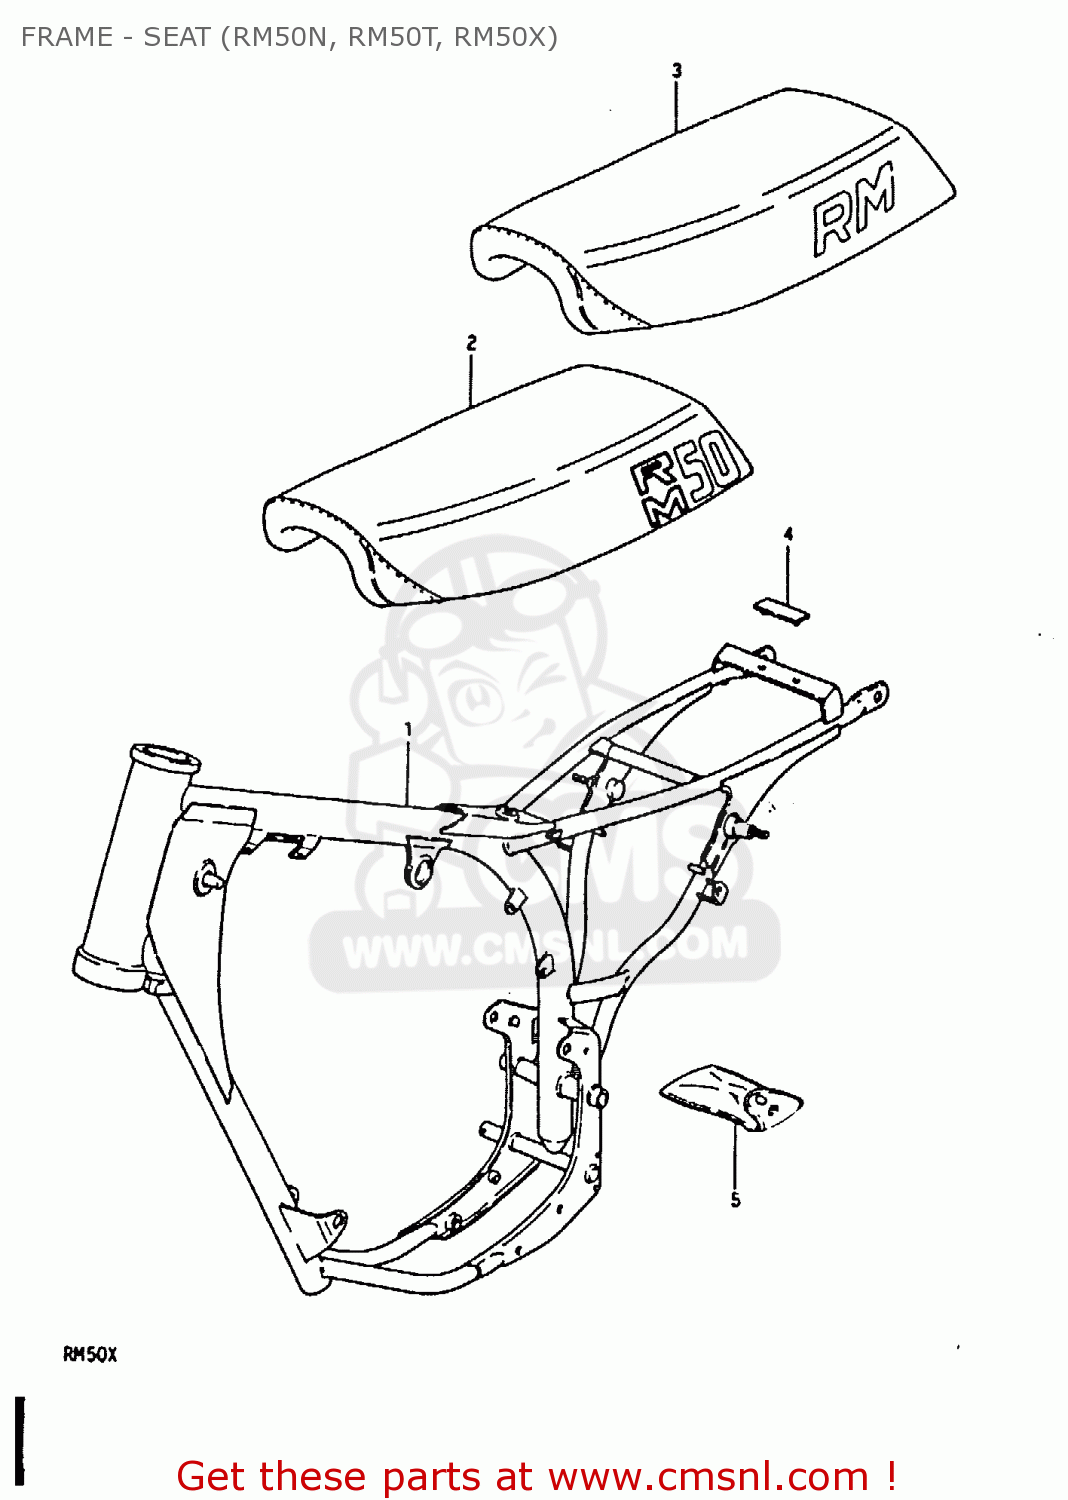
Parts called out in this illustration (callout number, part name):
1	FRAME
2	SEAT ASSEMBLY
3	SEAT ASSEMBLY
4	CUSHION
5	TOOL SET
